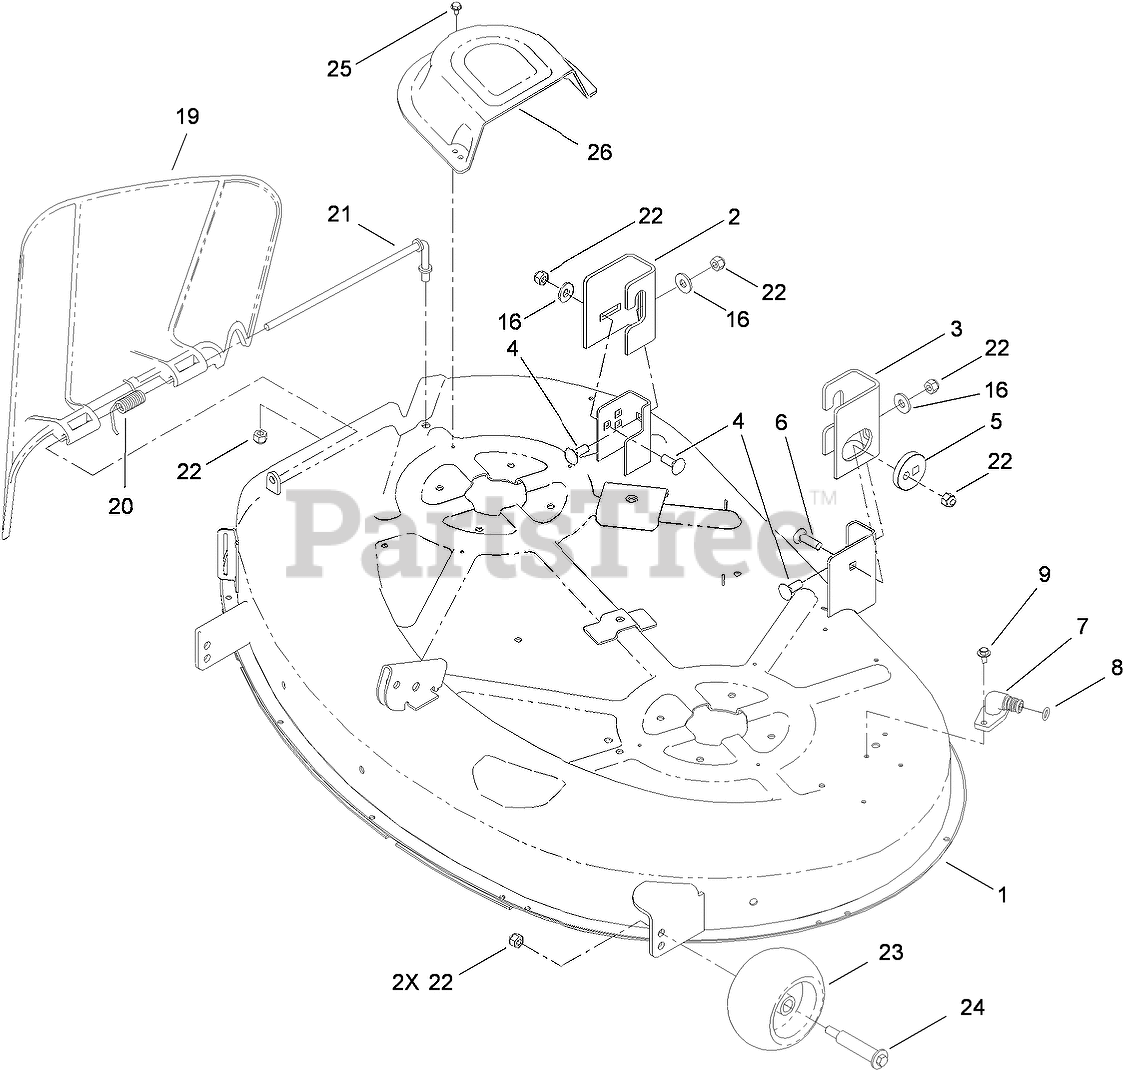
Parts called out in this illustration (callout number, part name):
1	42 INCH DECK AND DECAL ASM
2	BRACKET-HANGER, RIGHT REAR
3	BRACKET-HANGER, LEFT REAR
4	BOLT-CARR
5	ECCENTRIC
6	SCREW-CARR
7	FITTING-WASHOUT
8	O-RING
9	SCREW-HHFTF
16	WASHER-HARDENED
19	DEFLECTOR
20	SPRING-TORSION
21	ROD-PIVOT
22	NUT-LOCK, NI
23	ROLLER-SCALP, ANTI
24	BOLT-SHOULDER
25	SCREW-HWHTF
26	COVER-BELT
